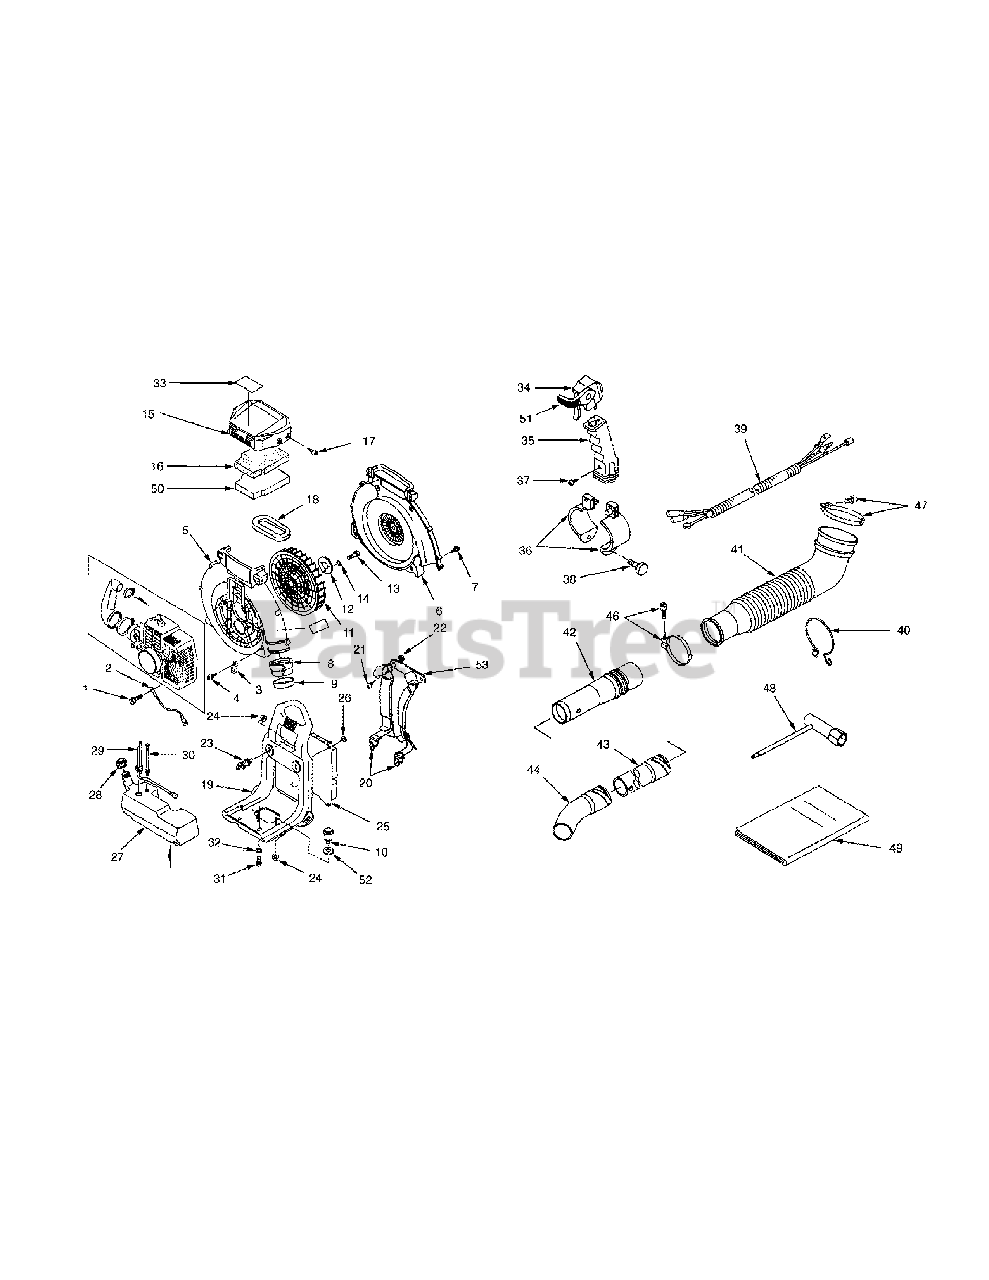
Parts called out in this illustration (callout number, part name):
2	Harness, Wire
14	Washer, Spring
15	Silencer Assembly
16	Element "A", Air Filter
21	Screw, M6x16
28	Cap Assembly, Fuel Tank
29	Filter, Assembly, Fuel
30	Valve Assembly, Reversing
31	Screw, M5x14
34	Lever, Throttle
36	Band Assembly
39	Wire Complete, Throttle
41	Pipe, Flexible
42	Pipe, Straight
43	Pipe, Straight
46	Band Assembly
47	Band Assembly
48	Wrench, Spanner Box 19
49	Manual, Operator's
50	Element "B", Air Filter
